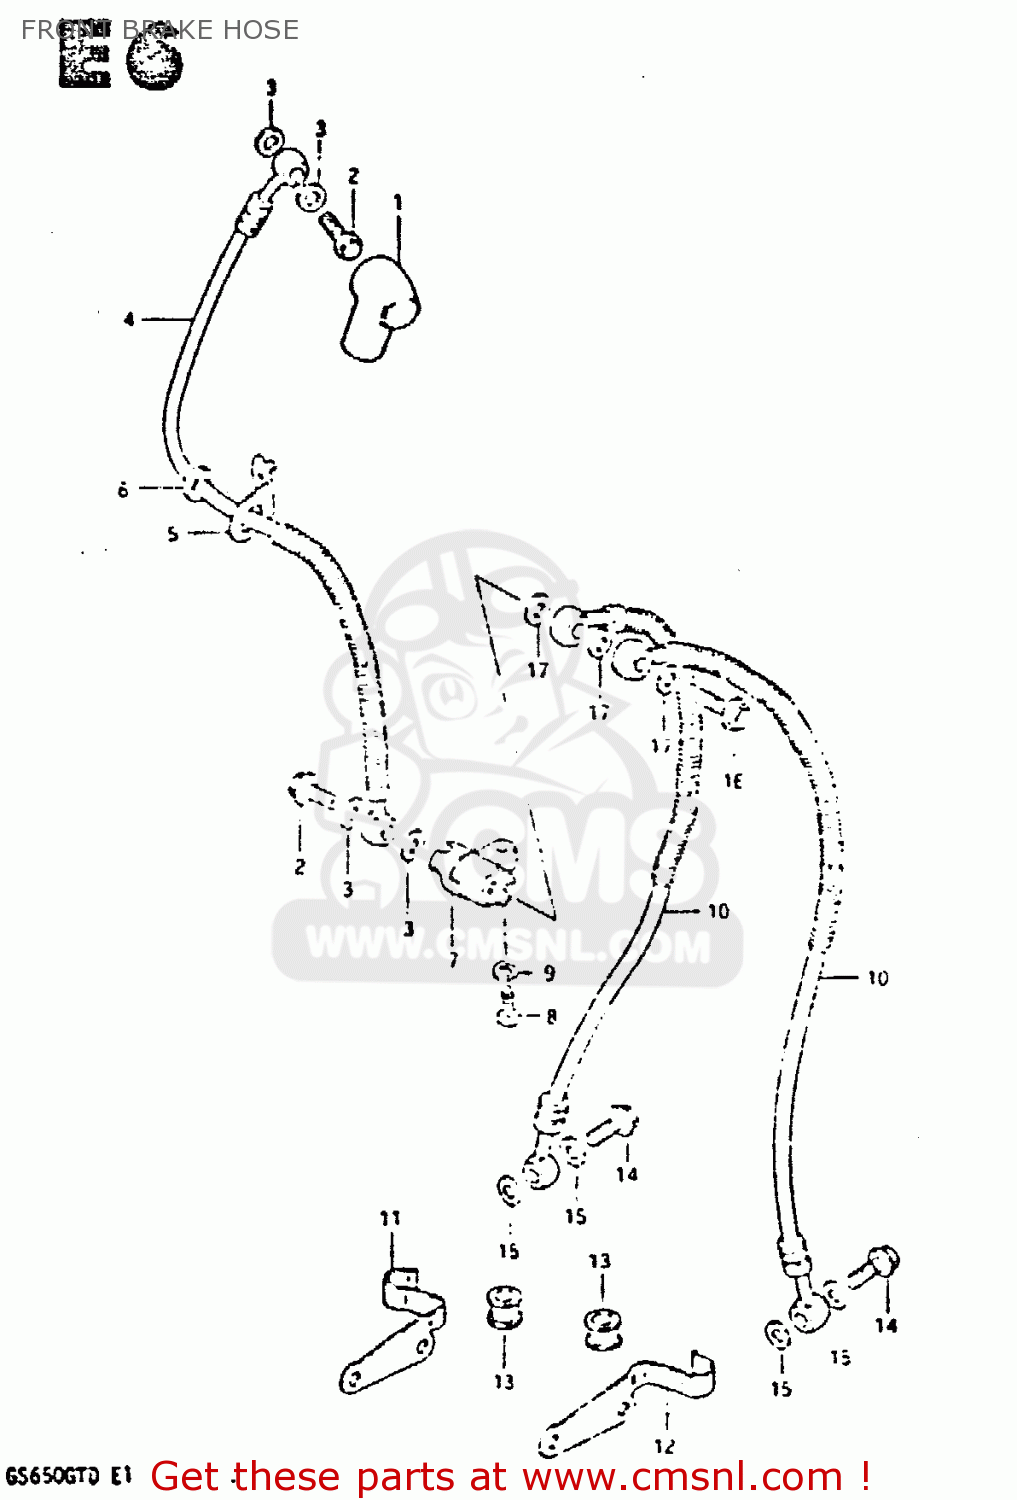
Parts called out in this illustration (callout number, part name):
1	BOOT,MASTER CYLINDER
2	BOLT,UNION
3	WASHER
4	HOSE,FRONT BRAKE
5	GUIDE,BRAKE HOSE NO.1
6	GROMMET
7	JOINT,BRAKE HOSE
8	BOLT
9	LOCK WASHER
10	HOSE,FRONT BRAKE
11	CLAMP,FRONT BRAKE HOSE
12	CLAMP,FRONT BRAKE HOSE
13	BUSH,BRAKE HOSE GUIDE,NO.2
14	BOLT,UNION
15	WASHER
16	BOLT,UNION
17	WASHER
